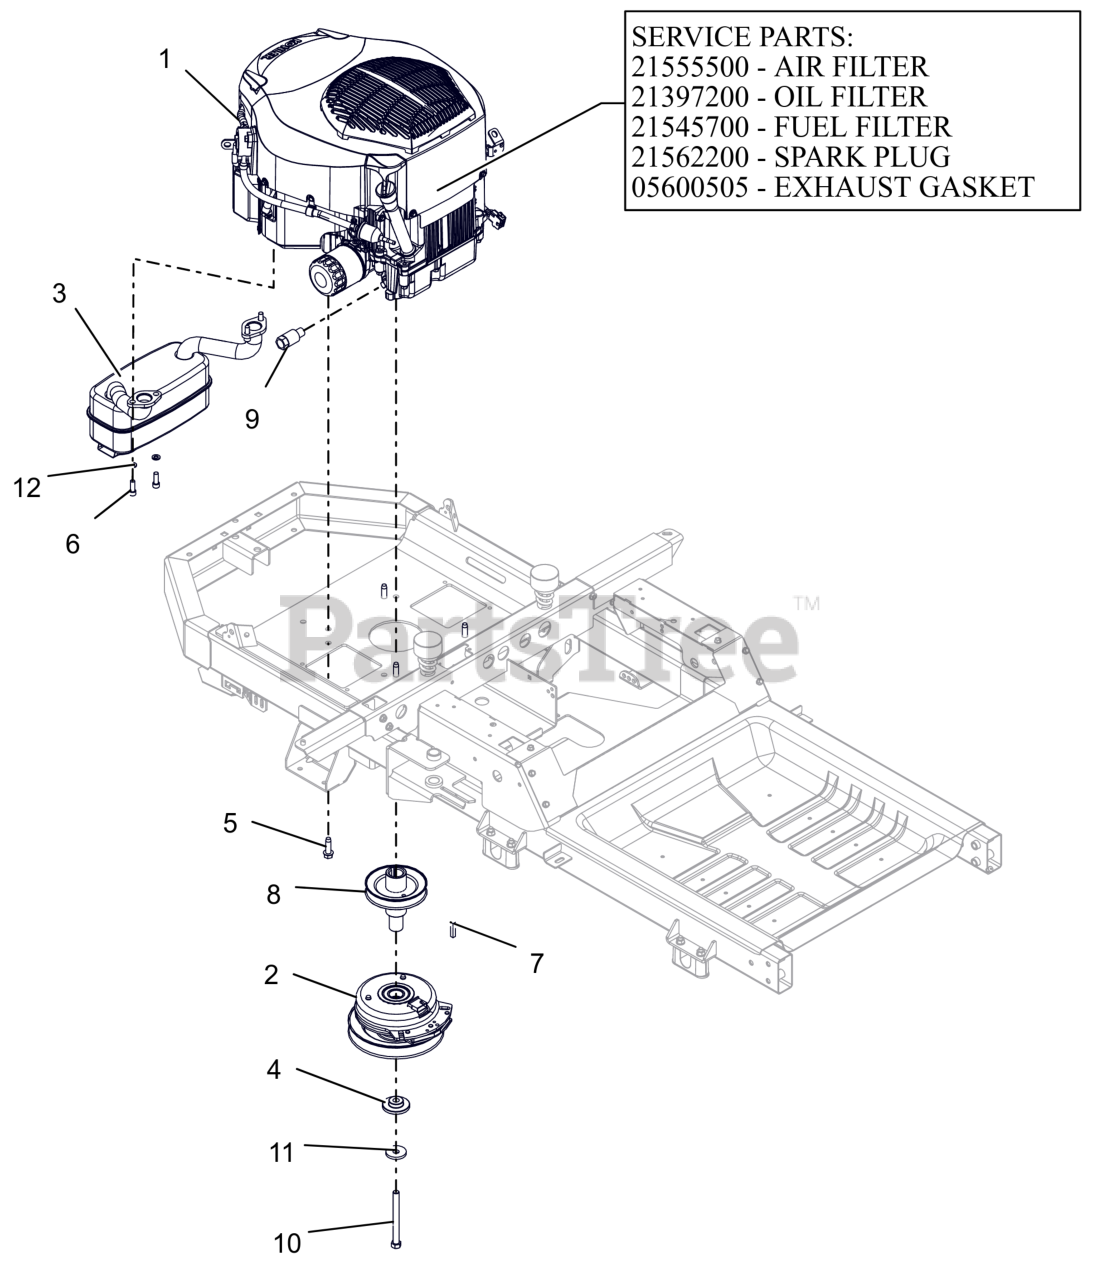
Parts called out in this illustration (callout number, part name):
1	ENGINE, KOHLER 24HP TWIN
1	AIR CLEANER, KOHLER
1	FILTER, OIL - KOH CV20
1	FILTER-FUEL KOHLER COURAGE PRO
1	PLUG, SPARK (RFI)
1	GASKET, MUFFLER KOHLER TWIN
2	CLUTCH,105FTLB MONOPOLE 6.83"
3	MUFFLER - KOHLER
4	BSHG-FLG .469X1.06X.574X2.0
5	SCR,TAP .375-16X1.25HWH TR ZCC
6	SCR, SKH .312-18X.875 GR8 ZCC
7	KEY-SQ .25 X 1.25 X .25 SAE
8	WLDMT, DRIVE SHEAVE-X
9	DRAIN, OIL
10	BLT, HEX .44-20X4.50 G8 ZCC NT
11	WASHER, 7/16" SPRING DISK
12	WSHR,LK-REG .312X.078 ZCC
